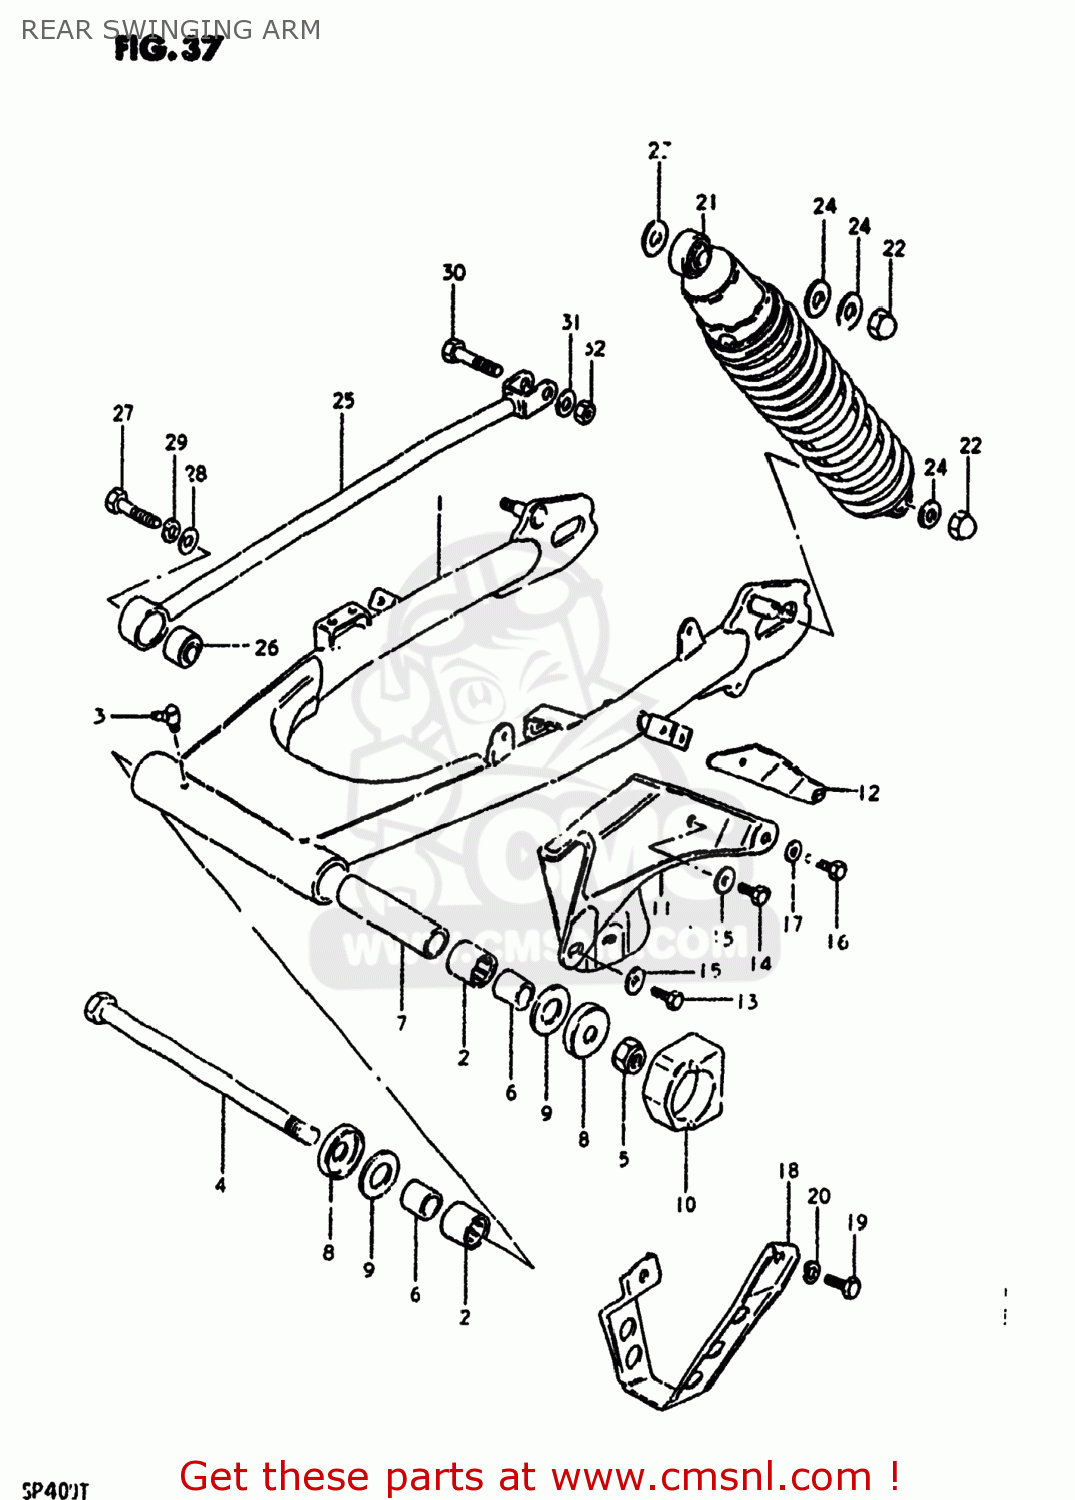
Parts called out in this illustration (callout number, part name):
1	SWING ARM ASSEMBLY,REAR
2	BEARING(22X29X20)
3	NIPPLE,GREASE
4	SHAFT,REAR SWING ARM
5	NUT 16MM
6	SPACER,RR SWGARM PIVOT
7	SPACER (16.2X21.7X142)
8	COVER,RR SWGARM DUST SEAL
9	WASHER
10	BUFFER,CHAIN TOUCH DEFENSE
11	CASE,CHAIN
12	REINFORCEMENT,CHAIN CASE
13	BOLT
14	BOLT(6X8)
15	WASHER
16	BOLT, UPPER
17	WASHER
18	GUIDE,CHAIN
19	BOLT 8X12
20	LOCK WASHER
21	ABSORBER ASSEMBLY,REAR SHOCK
22	NUT, LOWER LH
23	WASHER
24	WASHER
25	TORQUE LINK,REAR
26	BUSH
27	BOLT 10X40
28	WASHER
29	LOCK WASHER
30	BOLT 10X40
31	WASHER
32	NUT
